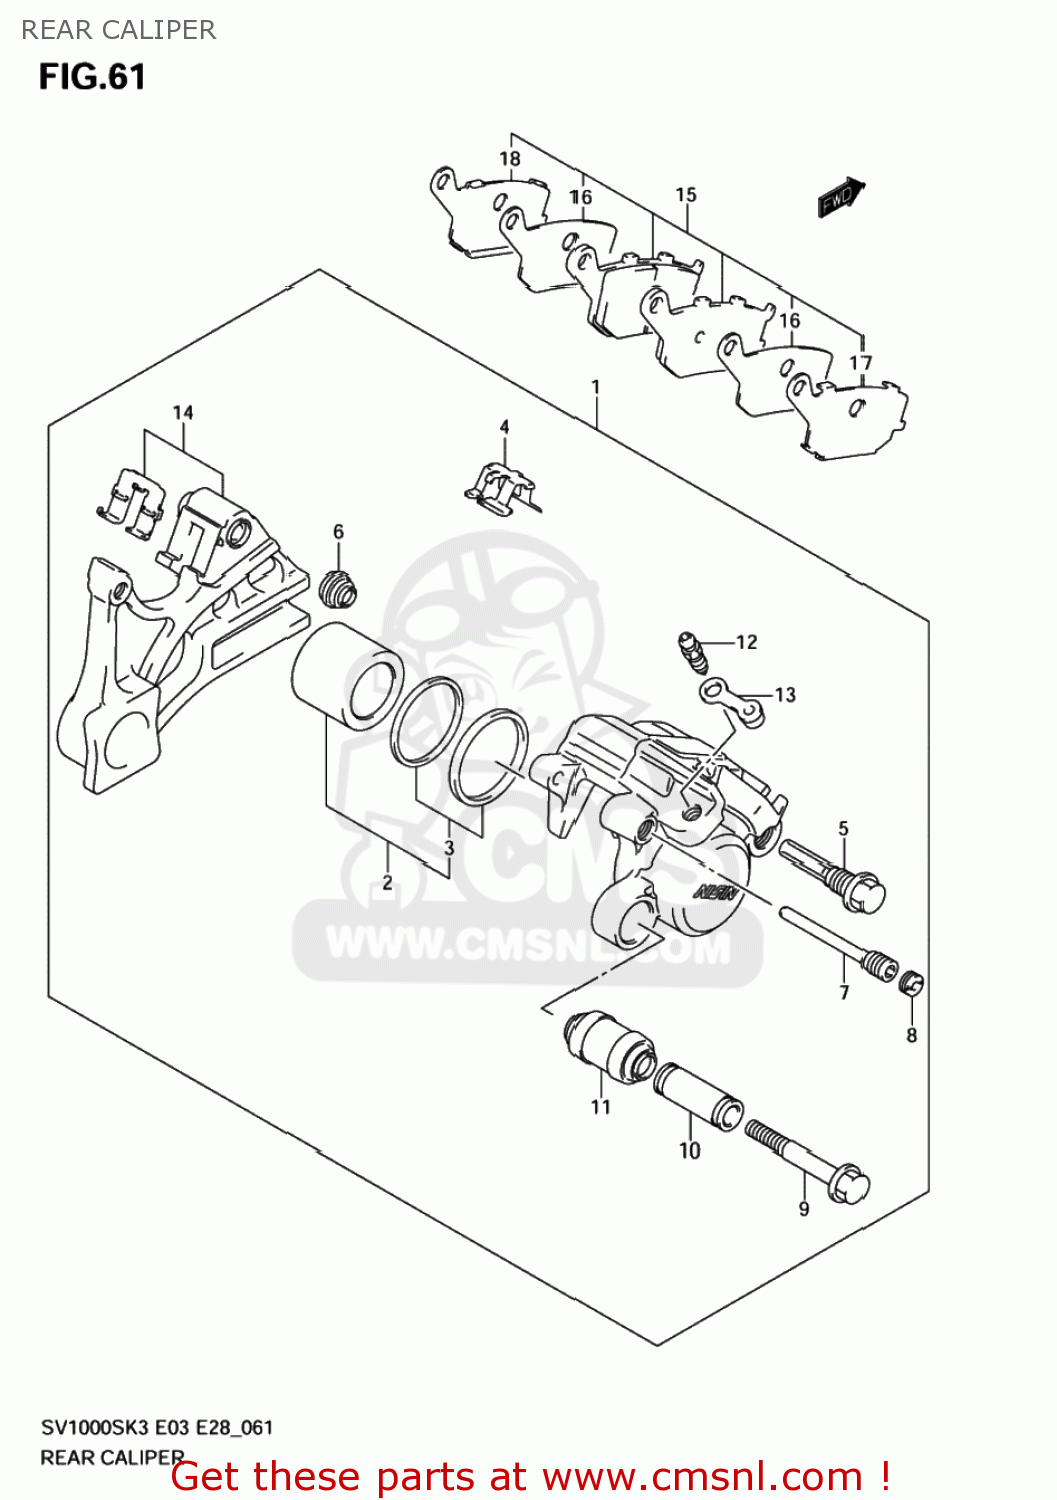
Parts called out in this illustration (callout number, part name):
1	CALIPER ASSY, REAR
2	PISTON SET
3	SEAL SET,PISTON
4	SPRING,PAD
5	BOLT
6	BOOT
7	PIN,PAD
8	PLUG,PIN
9	BOLT
10	SLEEVE
11	BOOT,SLEEVE
12	BLEEDER
13	CAP,BLEEDER
14	BRACKET
15	PAD & RETAINER
16	INSULATOR
17	RETAINER
18	RETAINER
